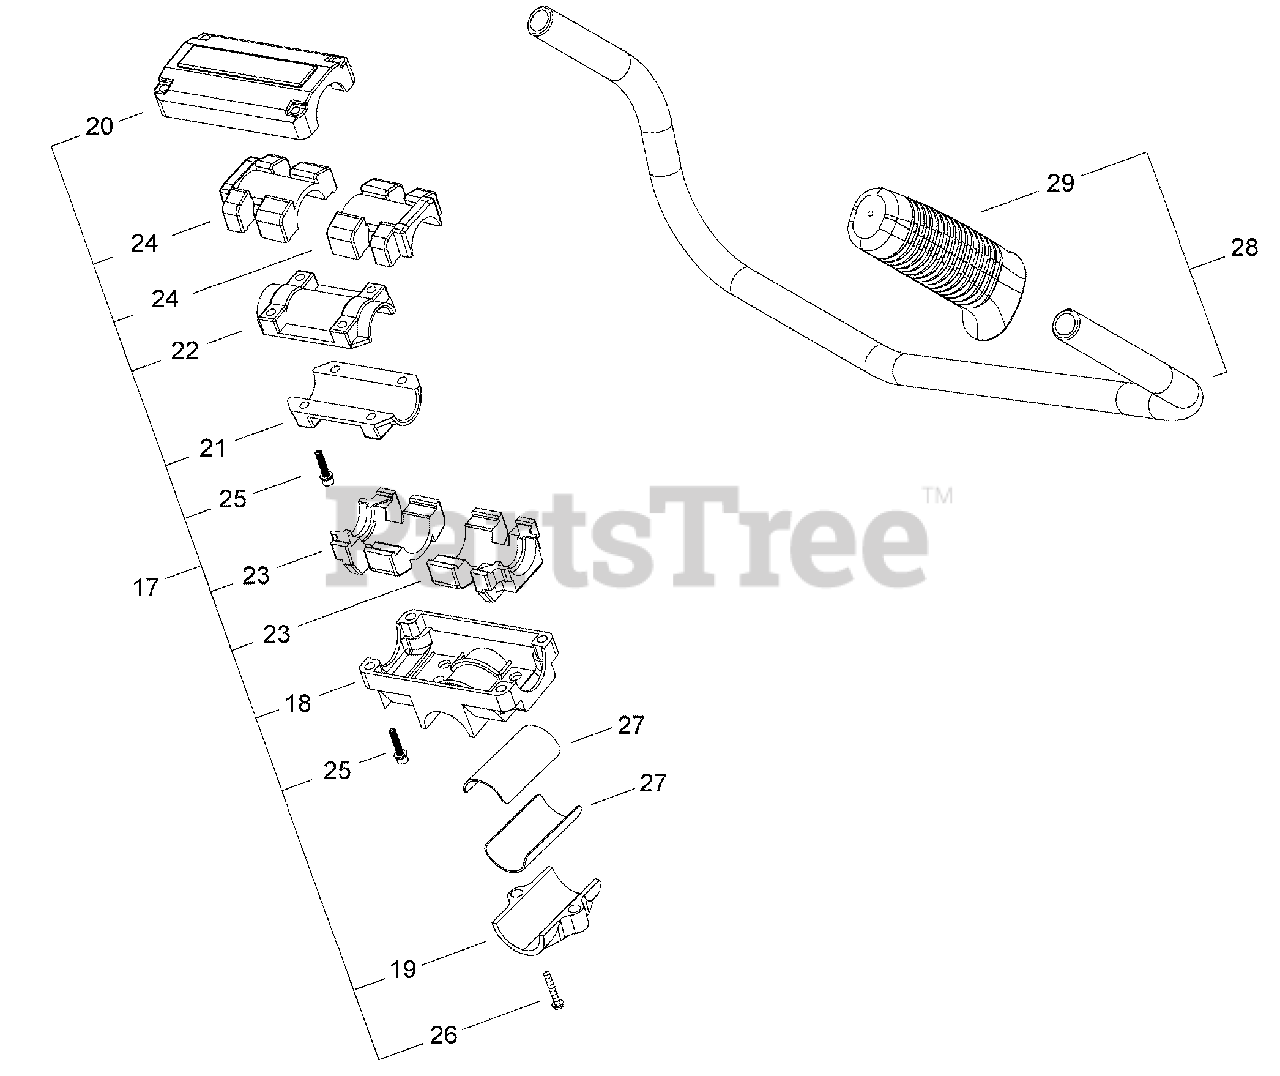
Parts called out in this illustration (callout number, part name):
17	BRACKET KIT, HANDLEBAR
18	BRACKET, LOWER
19	BRACKET, MOUNTING
20	BRACKET, UPPER
21	CLAMP, LOWER
22	CLAMP, UPPER
23	CUSHION, LOWER
24	CUSHION, UPPER
25	BOLT M5×25
26	SCREW M6×25
27	SPACER
28	HANDLEBAR ASSY
29	GRIP
